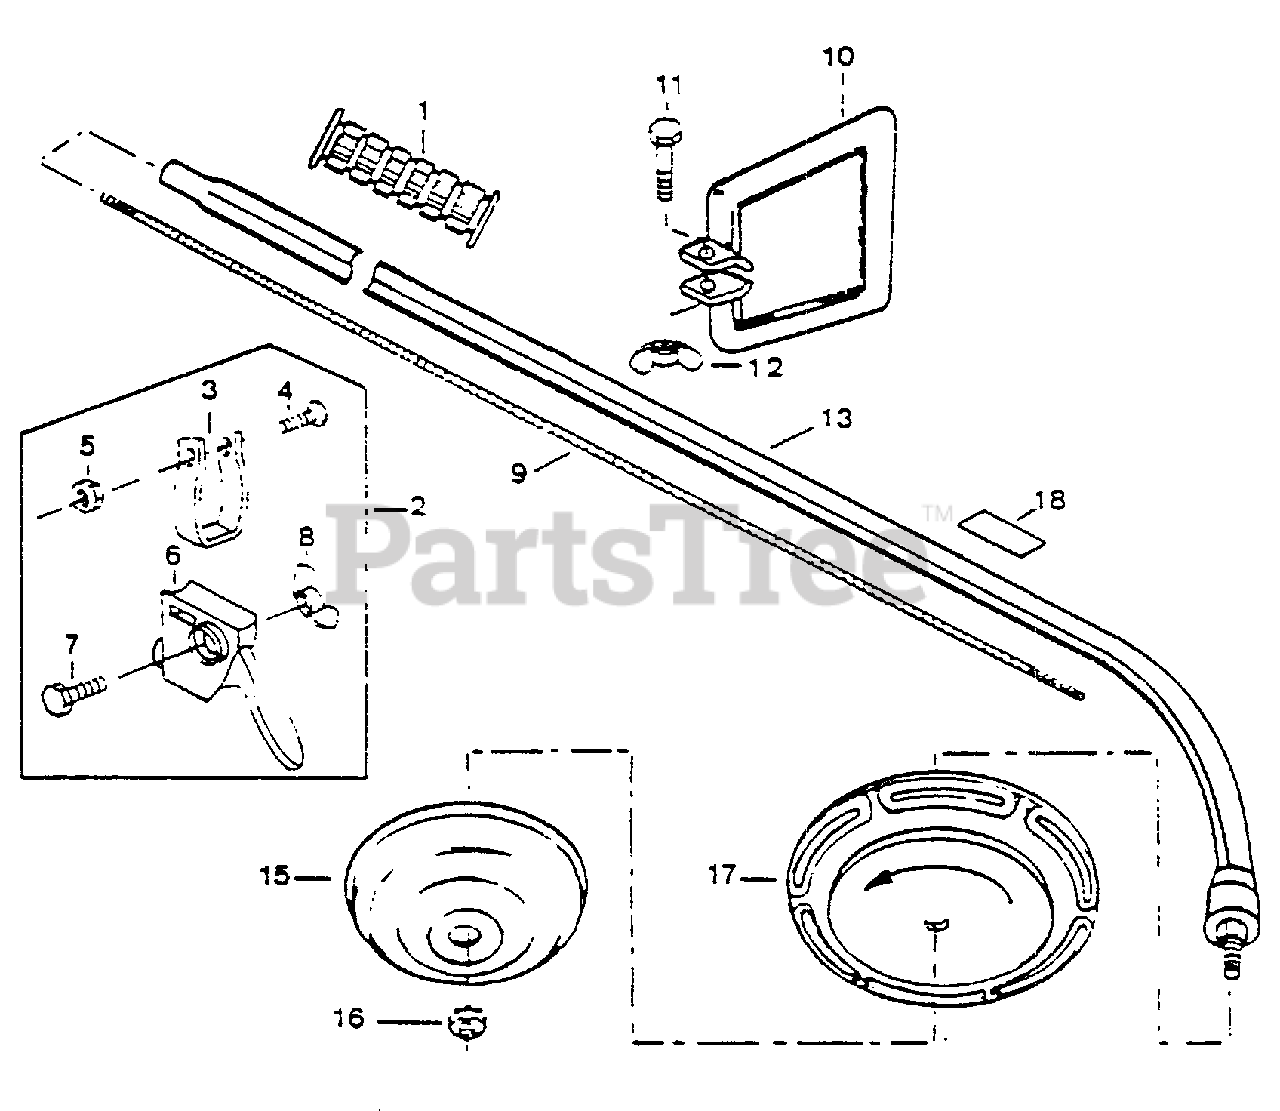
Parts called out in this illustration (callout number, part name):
2	CONTROL CABLE ASSY
3	CLAMP, THROTTLE
4	SCREW - 10-32 -- PAN HEAD
5	NUT - 10-32
6	LEVER THROTTLE W/BODY
7	SCREW - 10-32×1"
8	WINGNUT - 50-32
9	DRIVESHAFT - FLEXIBLE
10	GUIDE HANDLE
11	SCREW - 1/4-20 -- HEX HEAD
12	WINGNUT - 1/4-20
13	DRIVESHAFT ASSY - LEFT
14	MONO-HEAD W/0.080 LINE COMPLETE
15	LID
16	SCREW - 1/4-20
17	HEAD BODY MONO-HEAD
18	LABEL - LUBRICATION
